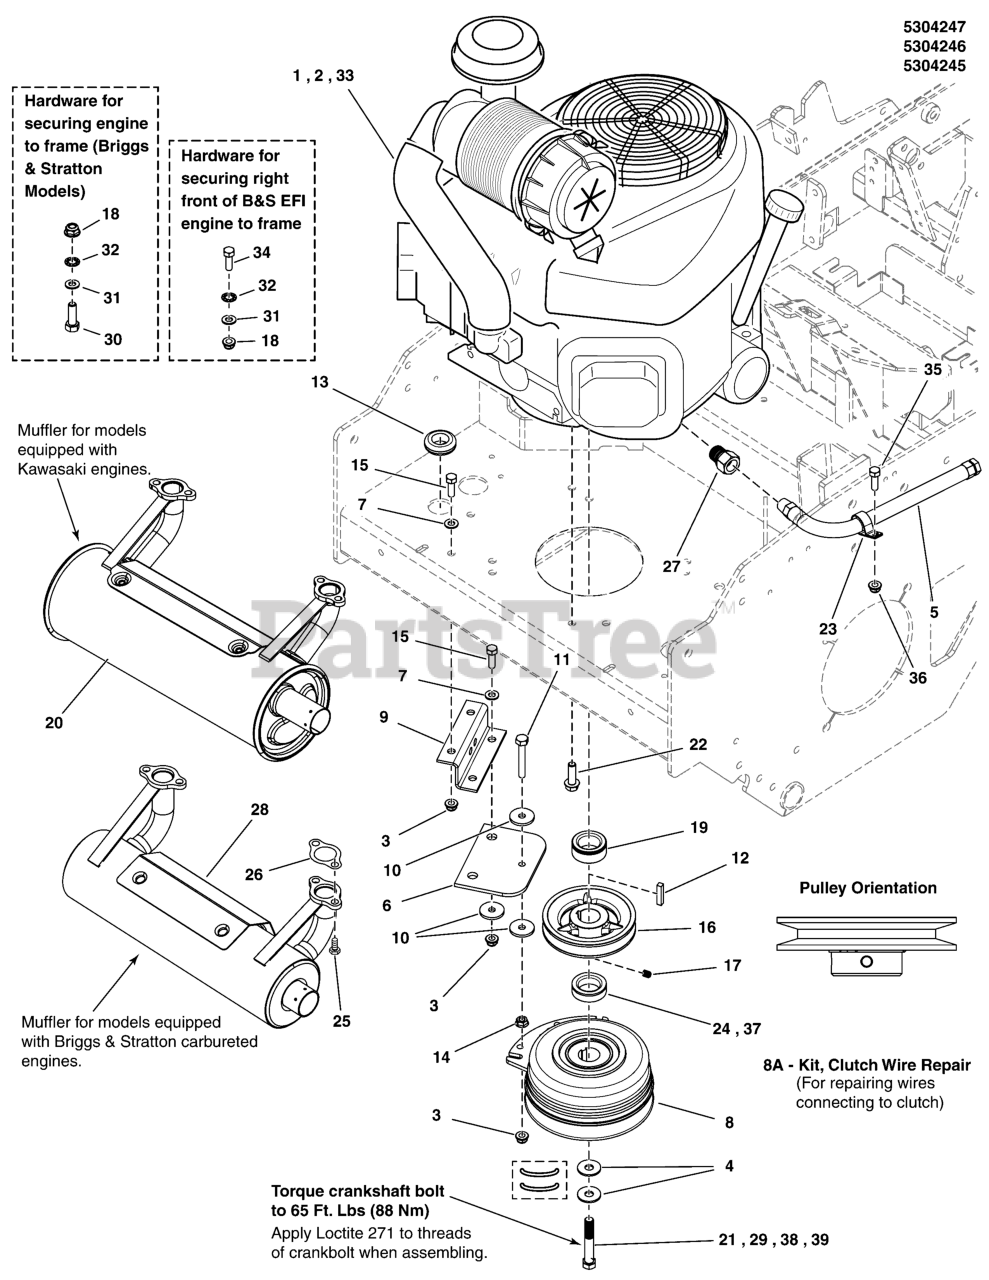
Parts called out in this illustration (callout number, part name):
1	ENGINE, KAWASAKI
2	ENGINE, BRIGGS & STRATTON, VANGUARD
3	NUT, 5/16-18 HEX NYLOCK FLANGE
4	BELLEVILLE WASHER 1.1875 X .442 X .089
5	HOSE, OIL DRAIN
6	CLUTCH ANCHOR PAD
7	WASHER, 5/16" SAE
8	CLUTCH,5218-221, WARNER
8A	KIT, CLUTCH WIRE REPAIR
9	ANCHOR, CLUTCH - BLK
10	WASHER, .34 X 1.25 X 10 GA
11	BOLT, 5/16-18 X 2-1/4 TFL, GD5 YZ
12	KEY, 1/4 SQ X 1-1/4
13	GROMMET, 7/8
14	NUT, 5/16-18 HEX SERRATED FLANGE (SMALL)
15	BOLT, 5/16-18 X 1 GD5 YZ
16	PULLEY, 4.75 OD X 1-1/8 BORE, BC-48
17	SET SCREW, 5/16-18 X 3/8, KNURL
18	NUT, 5/16-24, TOP LOCK FLANGE, GD8 PHOS
19	SPACER, 1.13 X 1.75 X .97
20	MUFFLER, KAWI, HORIZONTAL, 5" CAN
21	BOLT, CRANKSHAFT,7/16-20X2-3/4, GD8
22	BOLT, 3/8-16 X 1-1/4, SF, PLT W/PATCH
23	CLAMP, VINYL INSULATED
24	SPACER, 1.13 X 1.75 X .25
25	SCREW-HEX SEMS LOCK WSHR 5/16-18X0.875
26	GASKET, EXHAUST
27	ADAPTER-OIL DRAIN
28	MUFFLER, RIGHT OUTLET ASSY
29	BOLT, CRANKSHAFT,7/16-20X2-1/2, GD8
30	BOLT, 5/16-24 X 1-3/4, GD8, PHOS
31	WASHER, 5/16 LOCK CZ
32	WASHER, 5/16 INT. TOOTH LOCK
33	ENGINE, BRIGGS & STRATTON, EFI
34	BOLT, 5/16-24 X 1-1/2, GD8, PHOS
35	BOLT, 1/4-20 X 3/4 GD5 YZ
36	NUT, 1/4-20 HEX NYLOCK FLANGE
37	SPACER, 1.13 X 1.75 X .50
38	BOLT, CRANKSHAFT, 7/16-20 X 3, GD8
39	BOLT, CRANKSHAFT,7/16-20X2-3/4, GD8
